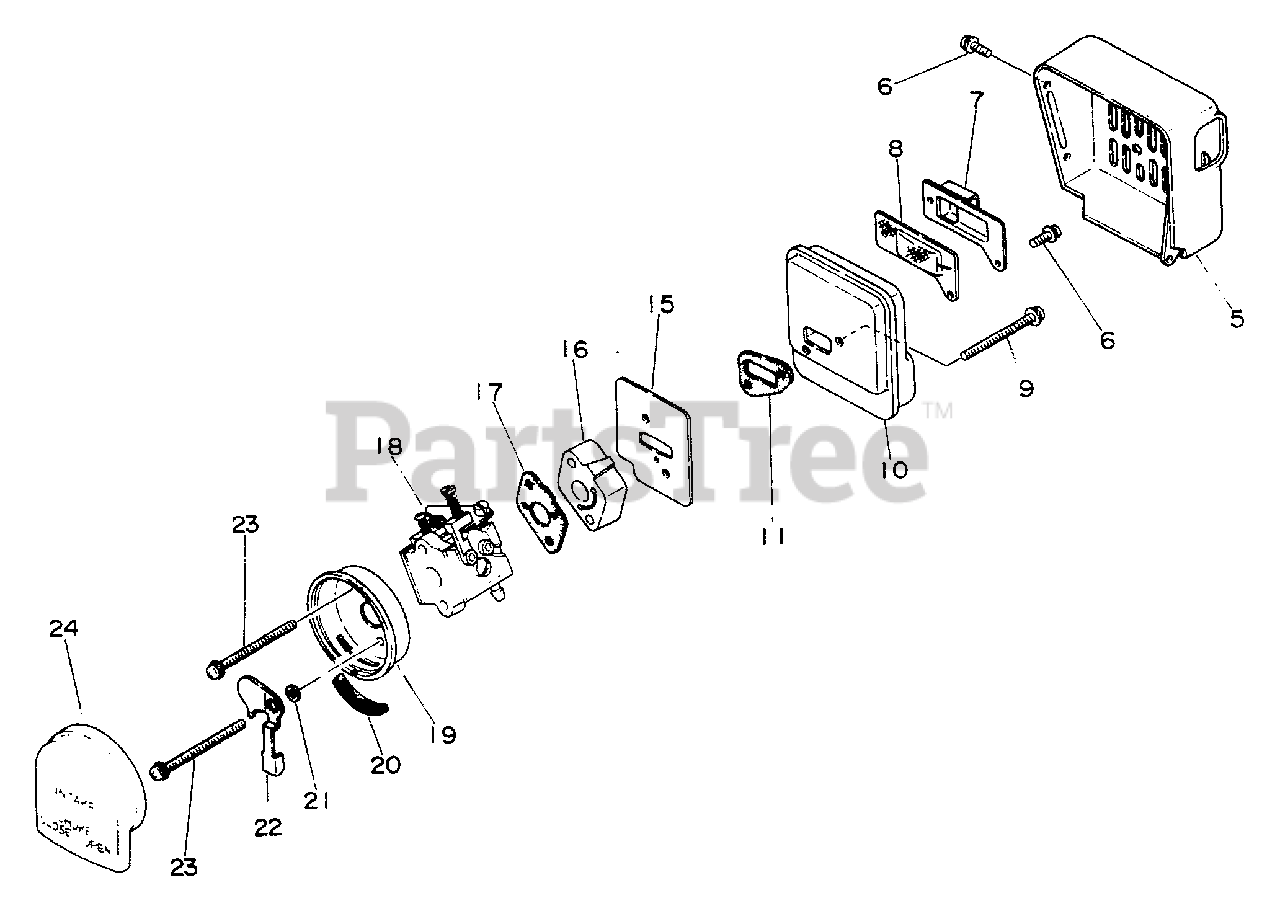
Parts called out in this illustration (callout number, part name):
5	COVER, MUFFLER
6	SCREW - 4X10
7	GUIDE, EXHAUST
8	SCREEN, SPARK ARRESTOR
9	SCREW - 5X40
10	CASE, MUFFLER
11	GASKET, EXHAUST
15	GASKET, INTAKE
16	INSULATOR, INTAKE
17	GASKET, INTAKE
18	CARBURETOR WA-168
19	CASE, AIR FILTER
21	WASHER - 5
22	SHUTTER, CHOKE
23	SCREW - 5X57
24	FILTER, AIR
